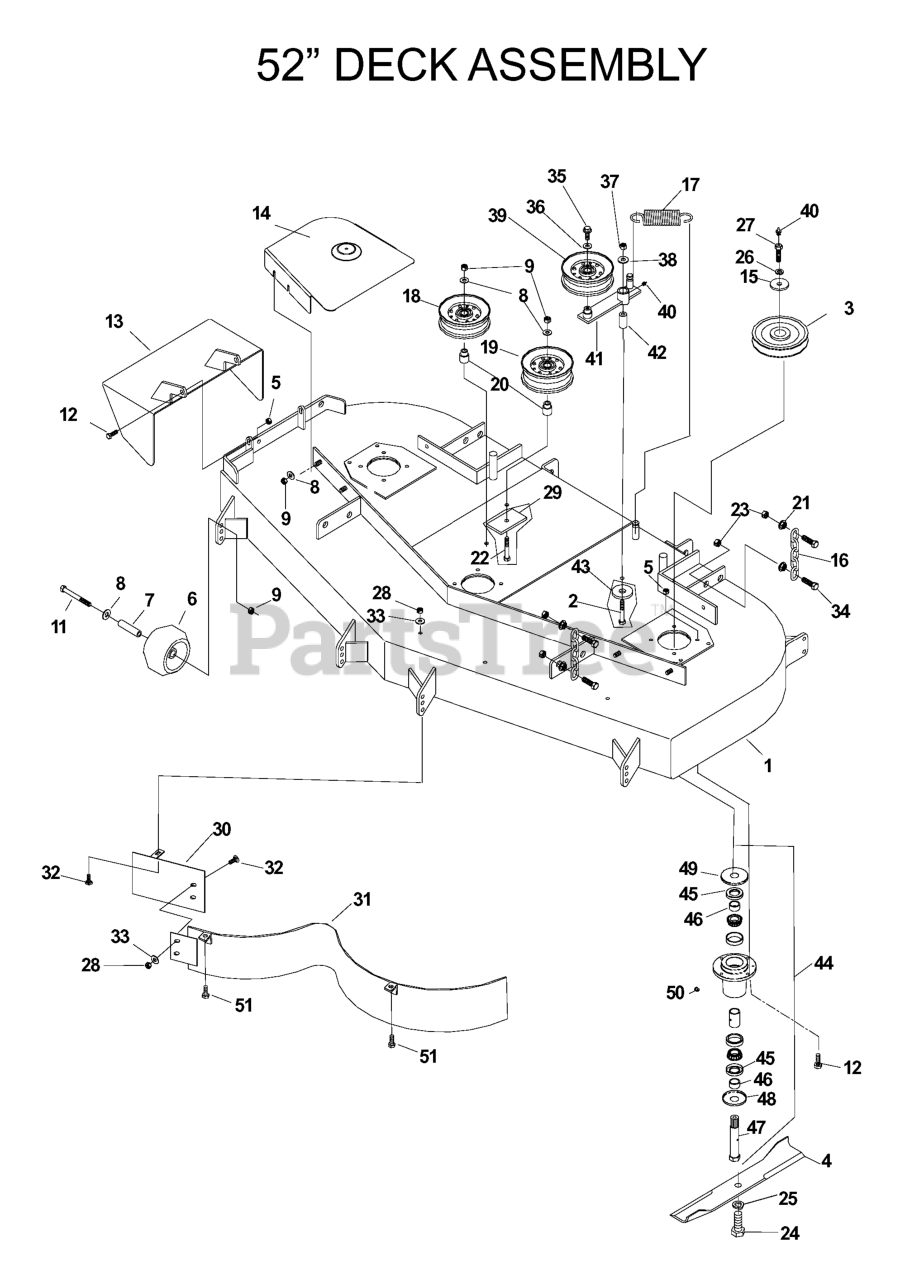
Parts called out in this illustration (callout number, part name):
1	DECK W/DECALS 52" HUS WSL
2	HCS 1/2C X 3 1/4
3	PULLEY - 52"
4	BLADE OEM 18"
5	NUT 5/16 NYLOC
6	ANTI-SCALP ROLLER
8	WASHER 3/8 FLAT
9	NUT 3/8-16 NYLOC
10	DECK BELT - 52"
11	HCS 3/8C X 3 1/2
12	HCS 5/16C X 1 1/4
13	DISCHARGE CHUTE ORANGE
14	RT 52 SHIELD, ORANGE
15	SPINDLE WASHER
16	LIFT CHAIN
17	DECK SPRING
18	IDLER PULLEY
19	IDLER PULLEY (TALL)
20	IDLER BUSHING
21	NUT 7/16C WHIZ
22	SCREW 3/8C X 2 3/4 HEX CAP
23	NUT 7/16C CENTERLOCK
24	HCS 5/8F X 1 1/4
25	LOCKWASHER 5/8
26	WASHER 7/16 LOCK
27	DRILLED BOLT 7/16-20 X 1 1/2"
28	NUT 5/16C CENTERLOCK
29	SUPPORT PLATE
30	CENTER BAFFLE - 52"
31	MAIN BAFFLE 52"
32	CARRIAGE BOLT 5/16C X 5/8"
33	WASHER 5/16 FLAT
34	HCS 7/16C X 1 1/2
35	4CS 3/8C X 1 SERRATED HEAD
36	WASHER 3/8 FLAT
37	NUT 1/2-13 HEX NYLOC ZD
38	WASHER 1/2 FLAT
39	IDLER PULLEY
40	ZERK
42	PIVOT BUSHING
43	WASHER, SUPPORT
44	SPINDLE ASSY - 52/61"
45	SHAFT SEAL
47	52/61 SPINDLE - SPLINED SHAFT
48	BOTTOM DUST CAP
49	TOP DUST CAP
50	PLUG-VENTED
51	HCS 5/16C X 3/4
539108910	LT 52 SHIELD ORANGE
